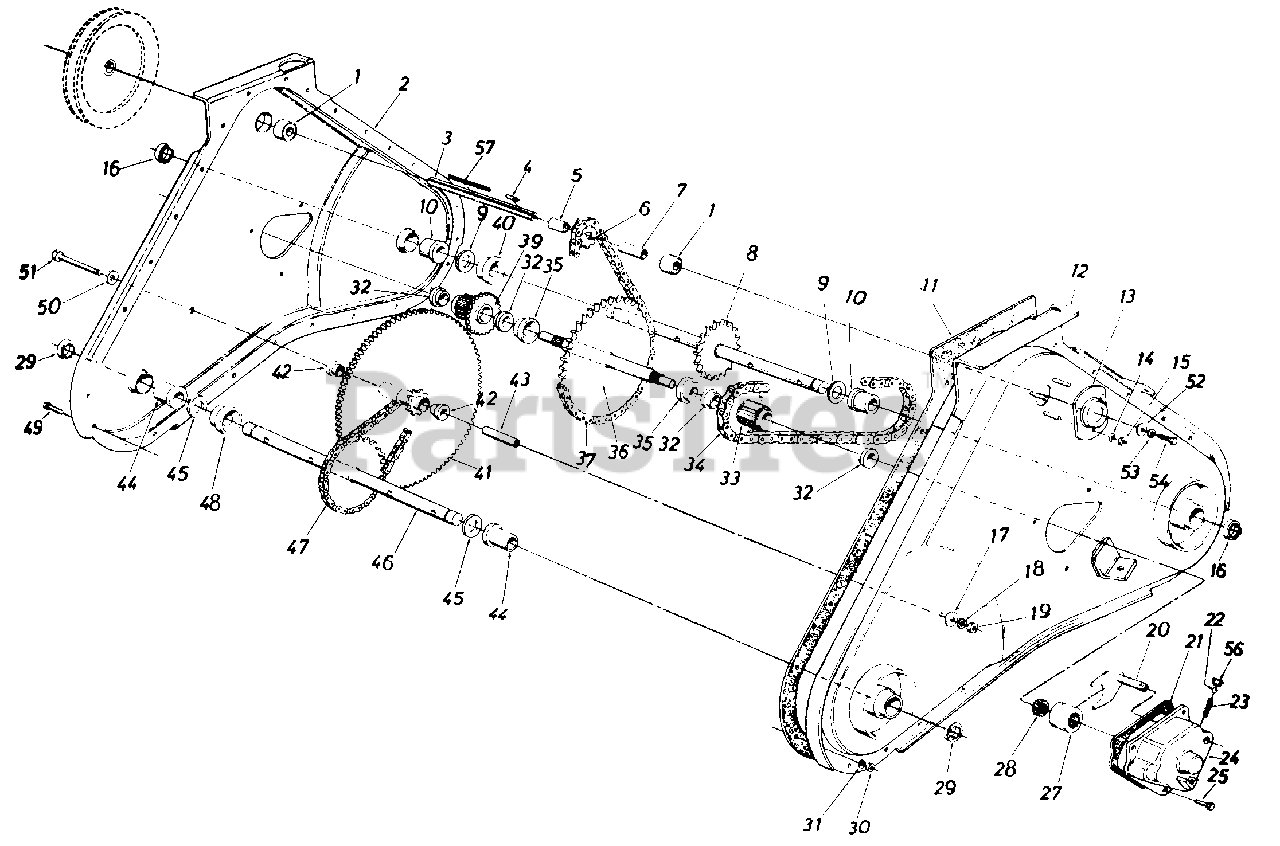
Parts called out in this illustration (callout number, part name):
1	Ball Bearing .62" I.D. x 1.38" O.D. x .44
2	Chain Case R.H. Half
3	Input Shaft .62" Dia.
4	Sq. Key 3/16" x 3/16" x .75" Lg.
5	Spacer.637" I.D. x .781" O.D. x .85" Lg.
6	Sprocket 9 Tooth x .62" Shaft
7	Spacer.637" I.D. x .781" O.D. x 1.44" Lg.
8	Tine Shaft Ass'y.
9	Fl-Wash. 1.28" I.D. x 1.62" O.D.
10	Flange Bearing 1.25" I.D.
11	Gasket Housing
12	Chain Case L.H. Half
13	Bearing Housing 1-3/8" O.D.
14	L-Wash. 1/4" I.D.*
15	Hex Nut 1/4-28 Thd.
16	Seal 1.25" I.D.
17	Belleville Wash.
18	L-Wash. 3/8" I.D.
19	Hex Cent. L-Nut 3/8-24 Thd.
20	Sh ift Yoke Ass'y. L.H.
21	Gasket Shift Housing
22	Ball Detent .250 Dia.
23	Compression Spring
24	Shift Housing L.H.
25	Hex Tap-Tite 5/16-18 x .75" Lg.
27	Clutch Dog
28	Clutch Dog Driver
29	Seal 1.0" I.D. x 1.38" O.D.
30	Hex Nut 1/4-28 Thd.
31	L-Wash. 1/4" I.D.*
32	Flange Brg. 1.00" I.D.
33	Sprocket Brg. Sleeve Ass'y.
34	#50 Chain 5/8" Pitch x 50 Links End less
35	Stepped Spacer 1.0" I.D. x 1.75" O.D.
36	Clutch Shaft Ass'y.
37	#420 Chain 1/2" Pitch x 58 Links Endless
39	Gear Bearing Sleeve Ass'y.
40	Spacer 1.25" I.D. x 2.0" O.D. x .68" Lg.
41	Sprocket and Gear Ass'y.
42	Flange Brg. .628" I.D. x .753" O.D.
43	Hub Sleeve .38" I.D. x .625" O.D.
44	Flange Brg. 1.00" I.D. x 1.188" O.D.
45	Fl-Wash. 1.0" I.D. x 1.62" O.D.
46	Axle Shaft Ass'y.
47	#420 Chain 1/2" Pitch 46 Links End less
48	Spacer 1.0" I.D. x 2.0" O.D.
49	Hex Bolt 1/4-28 x .62" Lg.
50	Belleville Wash.
51	Hex Bolt 3/8-24 x 2.75" Lg.
52	Fl-Wash. 5/16" I.D.
53	L-Wash. 5/16" I.D.
54	Hex L-Bolt 5/16-24 x .75" Lg.
56	Cap Plug .250" Dia.
57	Sq. Key 3116" x 2.0" Lg.
